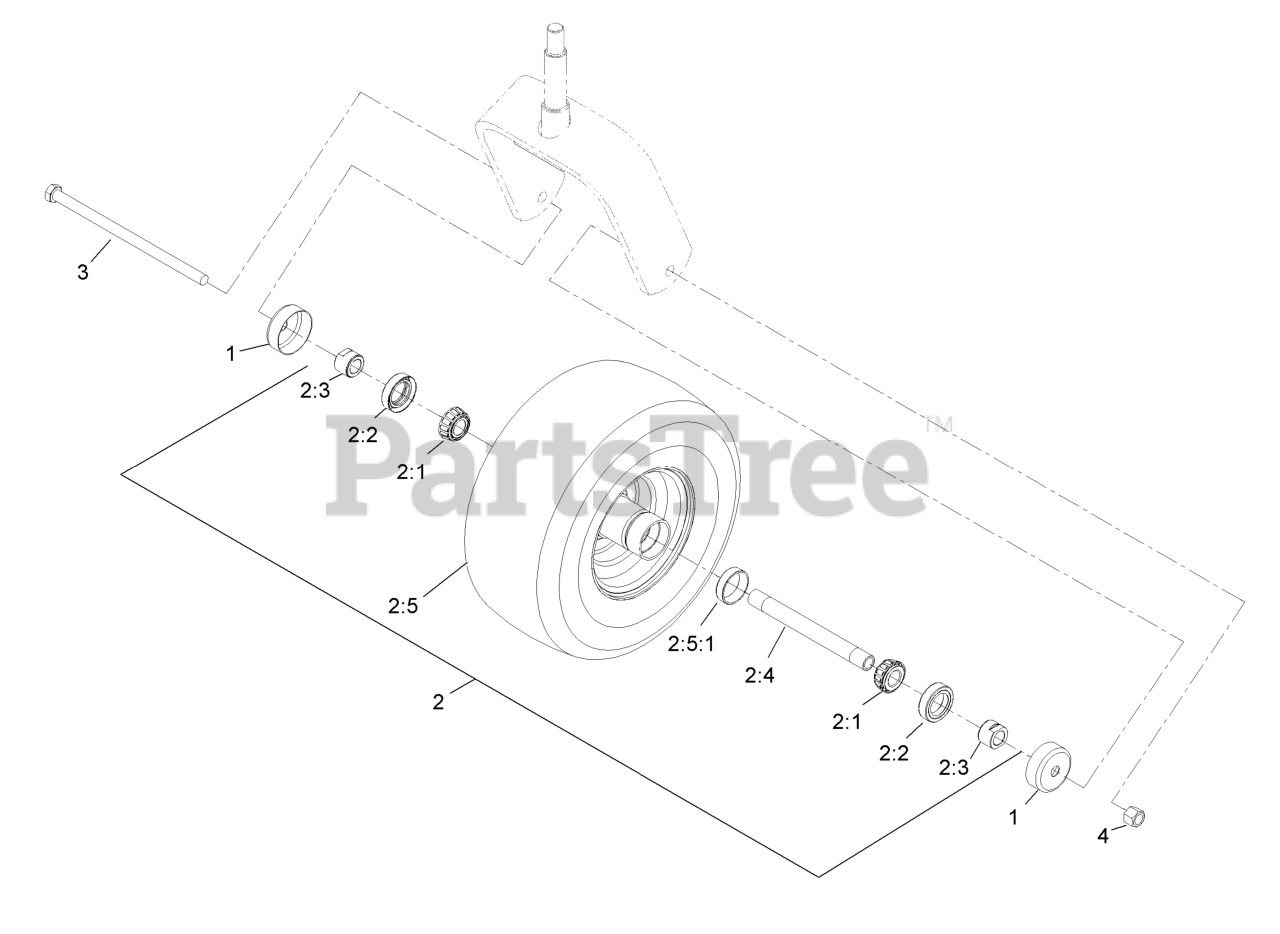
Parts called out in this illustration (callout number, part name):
1	GUARD-SEAL
2	Wheel And Tire ASM
2:1	BEARING-CONE, TAPERED ROLLER
2:2	SEAL-CASTER
2:3	SPACER-NUT
2:5	Wheel And Tire ASM
2:5:1	BEARING-CUP
3	SCREW-HH
4	NUT-LOCK, NI
